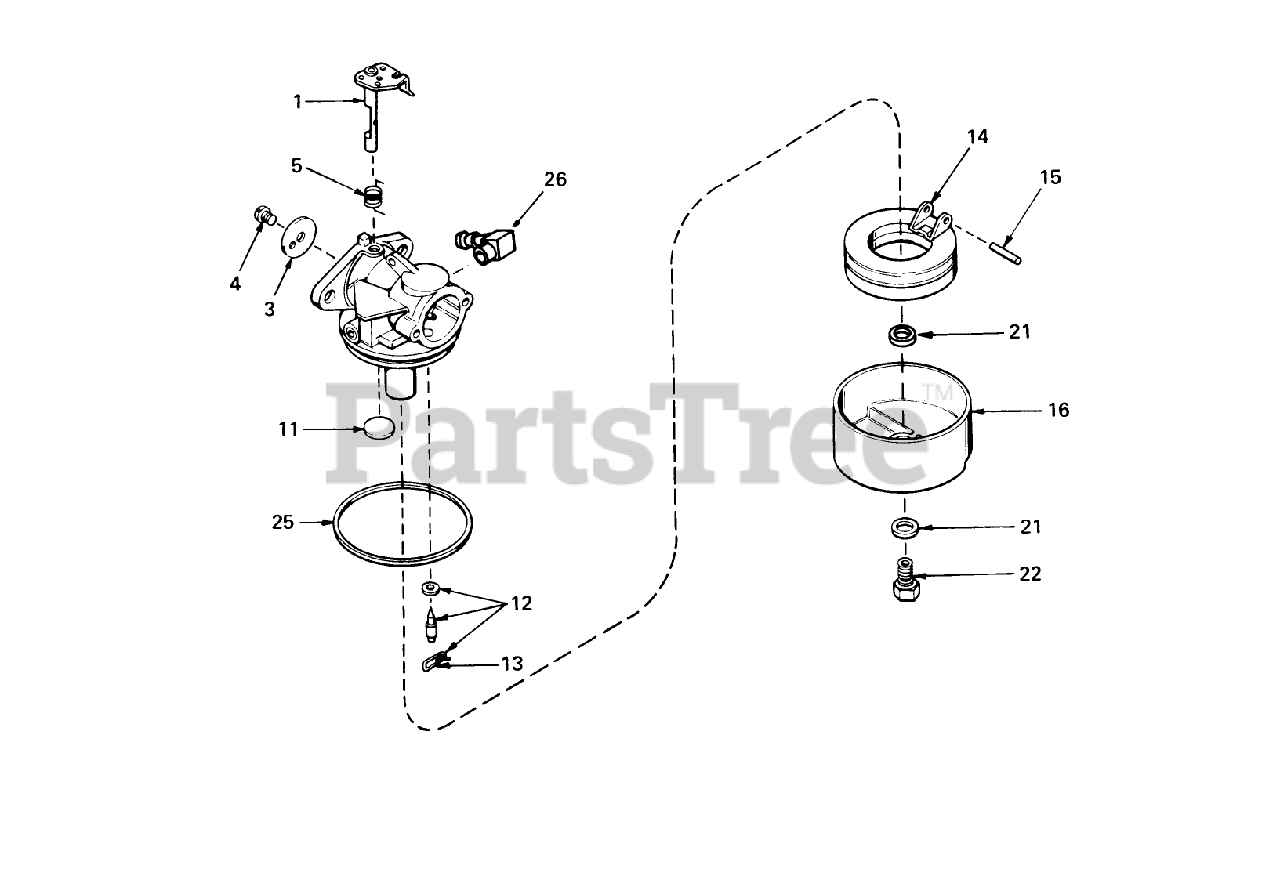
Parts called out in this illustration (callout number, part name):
1	Throttle Shaft and Lever ASM
3	Throttle-Shutter
4	Screw-Shutter
5	Spring, Return
11	Plug-Welch, Atmospheric Vent
12	Inlet Needle, Seat Clip Assy. (Incl. No. 13)
13	Clip-Spring
14	Float,Carburetor
15	Shaft-Float
16	Bowl Float
21	Gasket-Bowl
22	Nut, Float Bowl
25	O Ring-Bowl, Float
26	Fitting-Fuel
